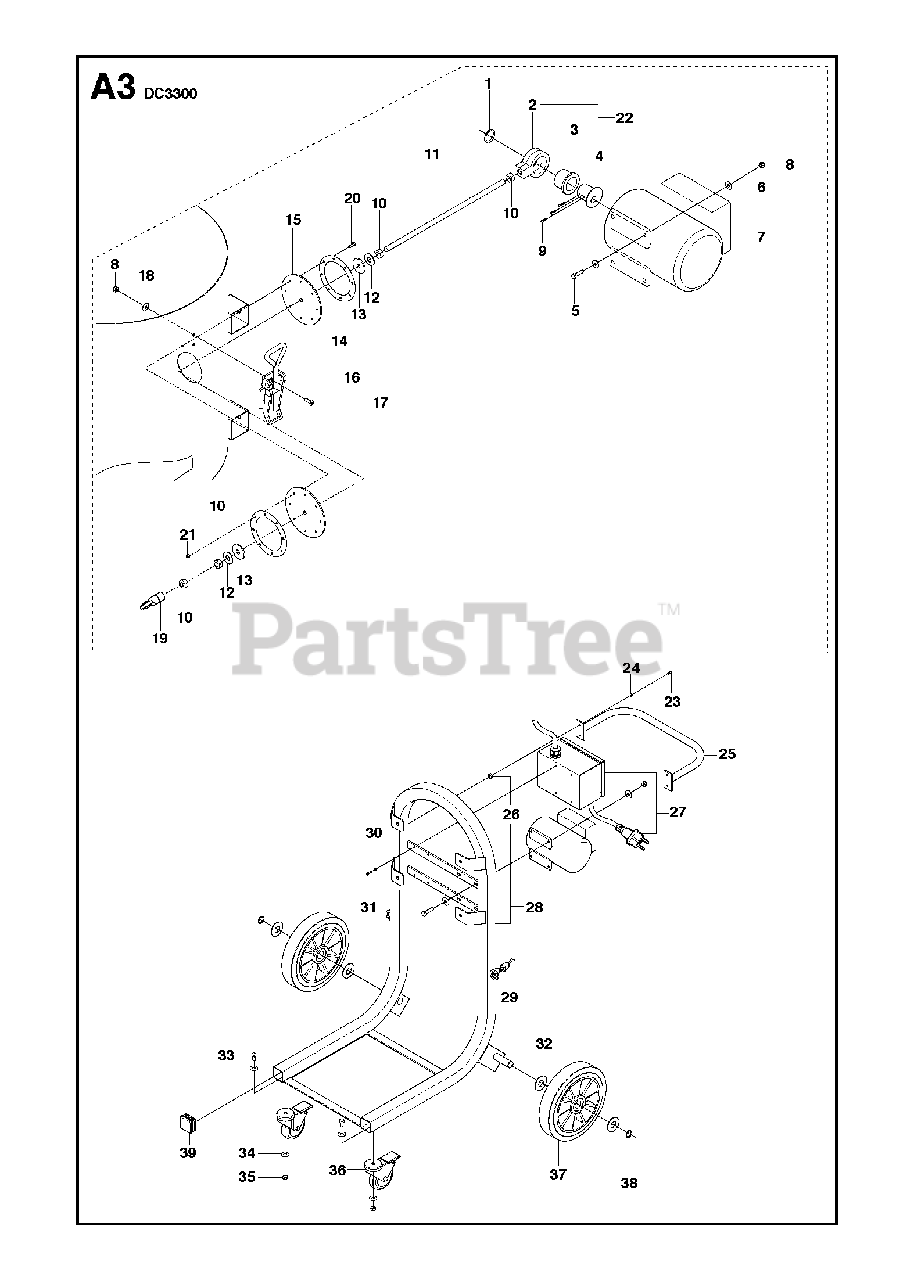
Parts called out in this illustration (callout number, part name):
8	HEXAGON LOCKING NUT
17	SCREW CRCSFM
21	HEXAGON LOCKING NUT
34	WASHER
